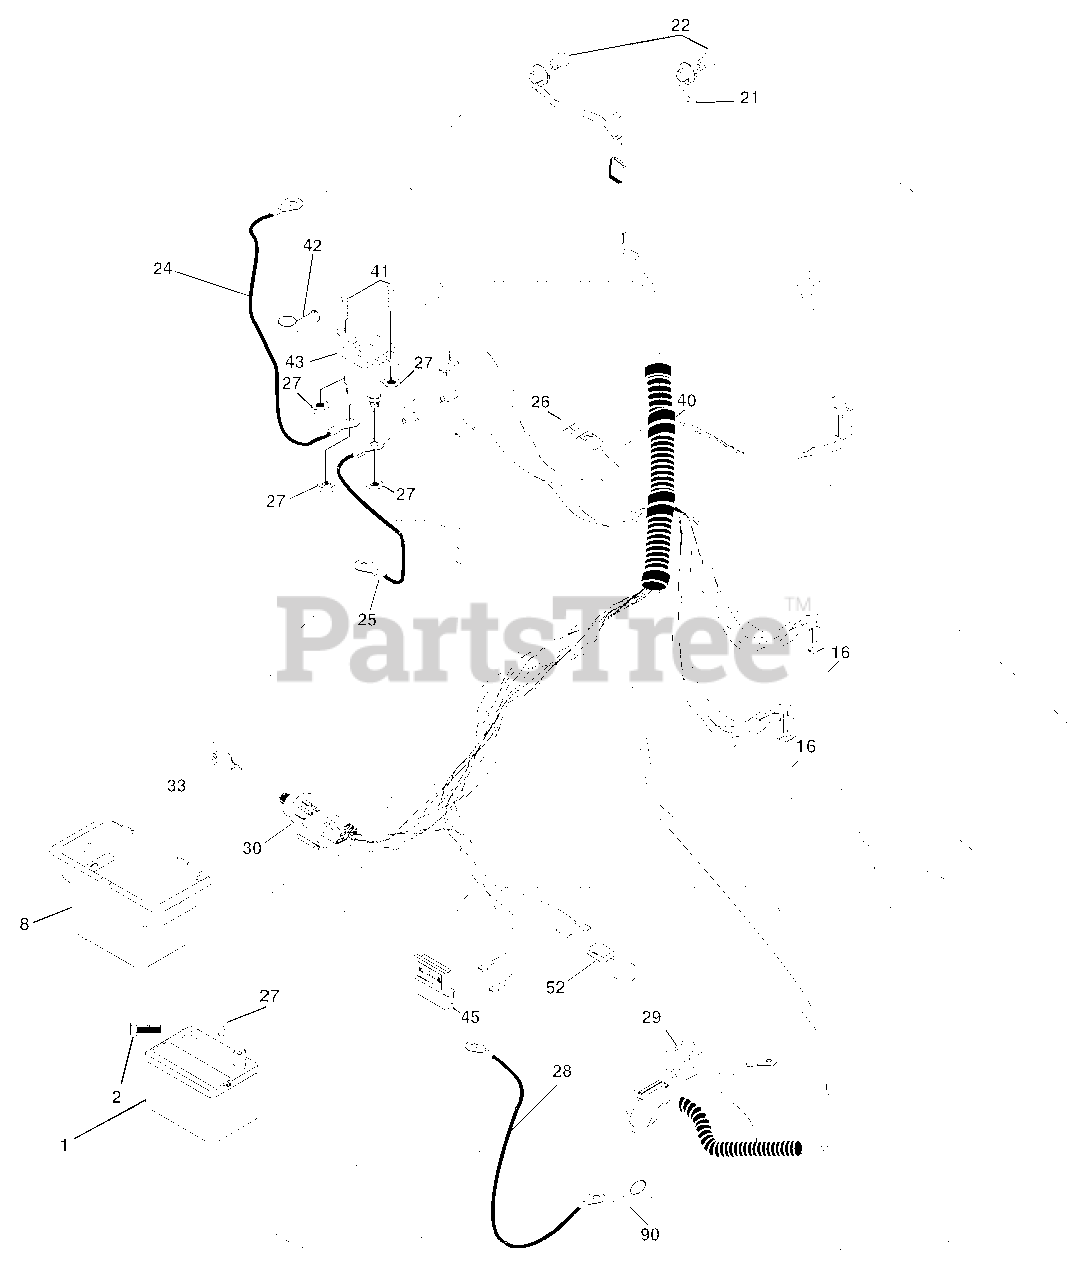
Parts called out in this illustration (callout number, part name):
1	Battery 12 Volt 25 Amp
2	Bolt Hex Hd 1/4-20 unc x 3/4
8	Box Battery
16	Switch Interlock Push -In
21	Harness Asm Light W/4152J
22	Bulb Light #1156
24	Cable Battery 6 Ga. 11"red
25	Cable Battery 6 Ga. w/16 wire,red
26	Fuse 20 AMP
27	Nut Keps Hex 1/4-20 unc
28	Cable Ground 6 Ga. 12" black
29	Switch Plunger Nc Gray
30	Switch Ign
33	Key Ign
40	Harness Ign
41	Bolt Blk Fin Hex 1/4-20 x 1/2
42	Cover Terminal Red
43	Solenoid
45	Ammeter
52	Protection Wire Loop
90	Cover Terminal
